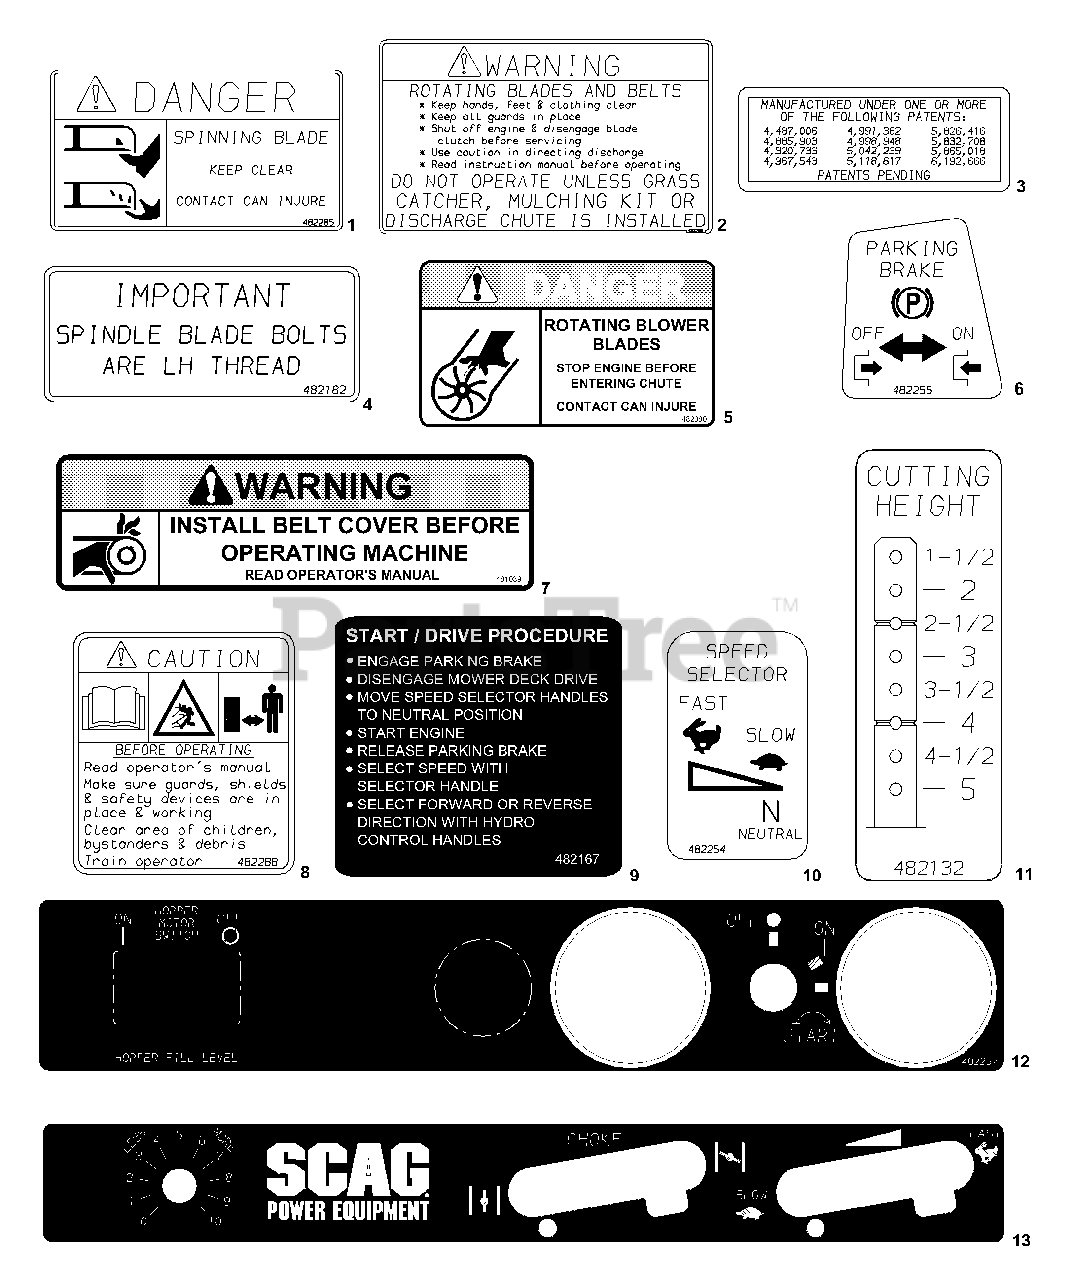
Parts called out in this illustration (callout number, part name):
1	Decal, Danger-Spining Blades
2	Decal, Warning-Rotating Blades
3	Decal, Patents
4	Decal, Blade Bolts LH Thread
5	Decal, Rotating Blades
6	Decal, Parking Brake
7	Decal, Belt Cover
8	Decal, Bystanders & Read Operator's Manual
9	Decal, Start and Drive Procedure
10	Decal, Forward Speed Selector
11	Decal, Cutting Height
12	Decal, Upper Instrument Panel - Kohler
13	Decal, Lower Instrument Panel
